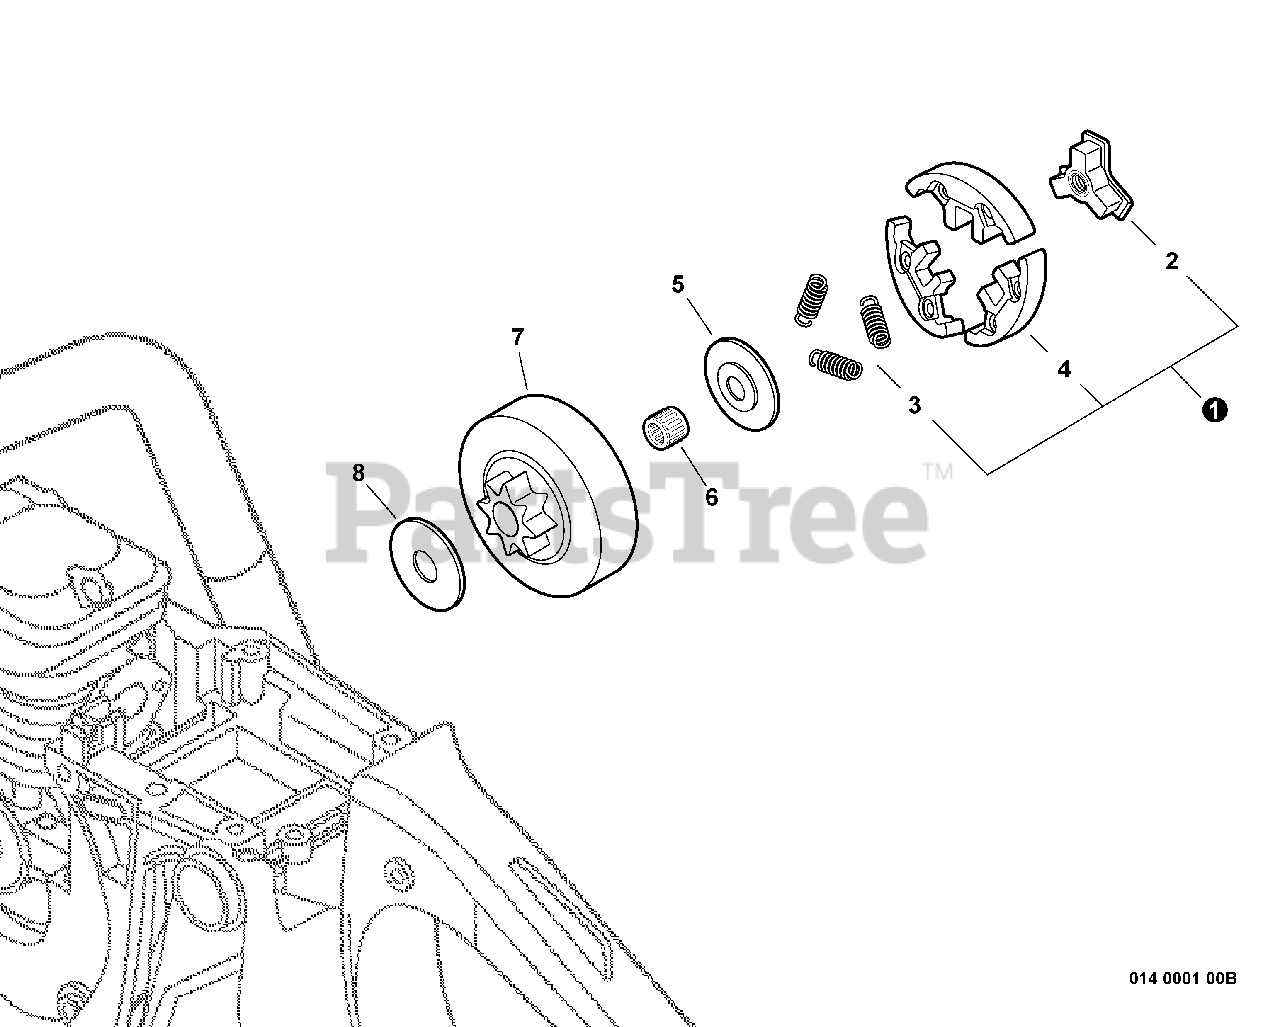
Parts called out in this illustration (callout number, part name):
1	CLUTCH ASSY
2	HUB, CLUTCH
3	SPRING, CLUTCH
4	CLUTCH SHOE SET
5	PLATE, CLUTCH
6	BEARING, NEEDLE
7	DRUM, CLUTCH
